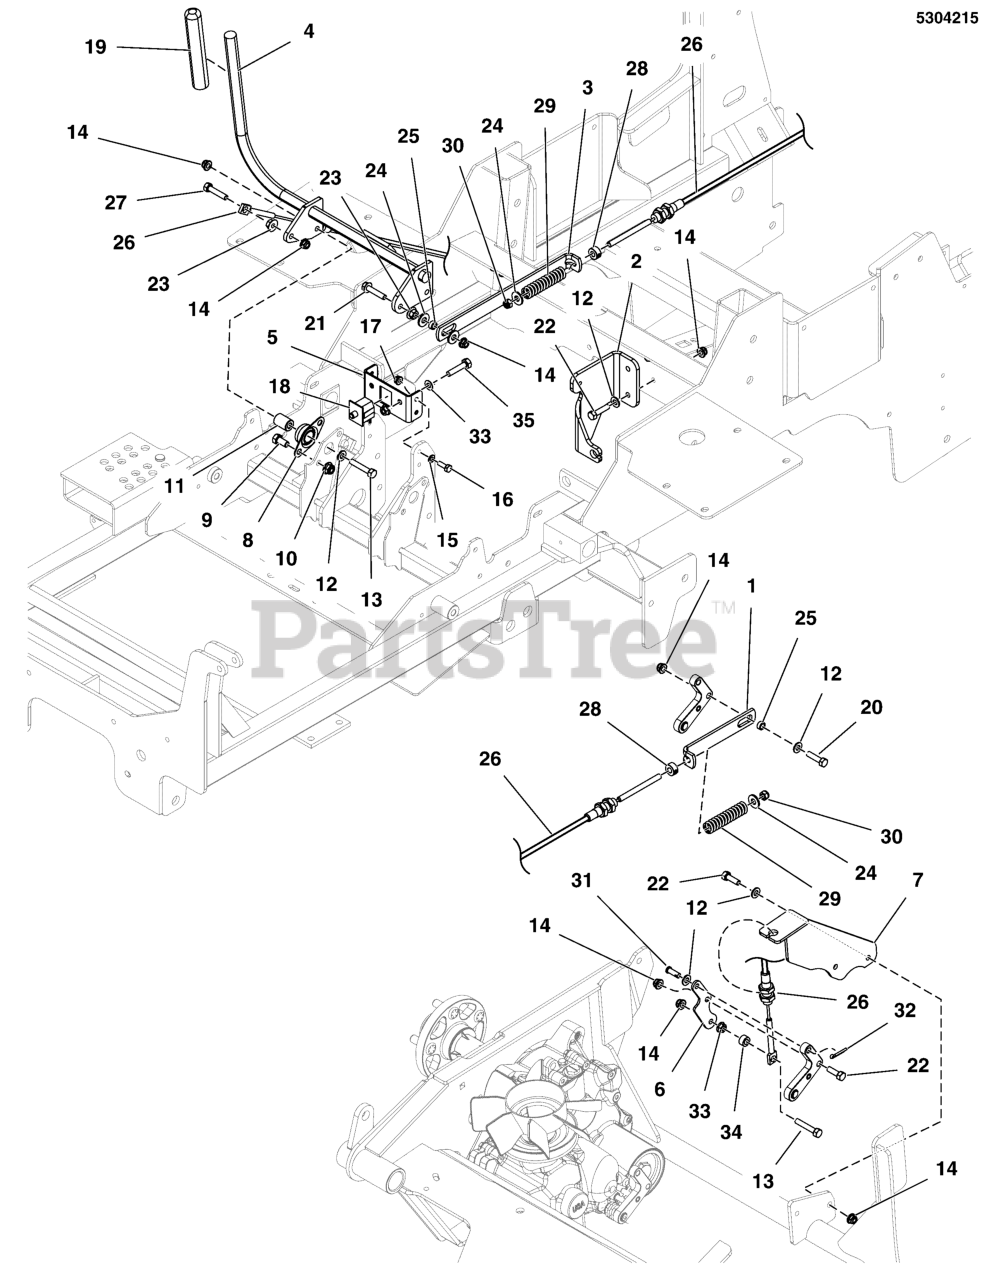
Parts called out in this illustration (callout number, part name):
1	LINK, BRAKE LOCK, RH, IS2600Z - BLK
2	MOUNT, BRAKE CABLE - RED
3	LINK, BRAKE, IS2600 - BLK
4	WELD, BRAKE SHAFT, IS2600 - BLK
5	PLATE, BRAKE STOP - RED
6	PLATE, BRAKE ARM, IS2100 - BLK
7	BRACKET, Mounting
8	BEARING, 3/4" FLANGED, BRONZE
9	BOLT, 3/8-16 X 3/4" GD5 CZ
10	NUT, 3/8-16 HEX NYLOCK FLANGE
11	SPACER, .32 X .75 X 1.06, PM
12	WASHER, 5/16" SAE
13	BOLT, 5/16-18 X 1-3/4 GD5 CZ
14	NUT, 5/16-18 HEX NYLOCK FLANGE
15	WASHER, 1/4 SAE
16	BOLT, 1/4-20 X 3/4 GD5 CZ
17	NUT, 1/4-20 HEX NYLOCK FLANGE
18	SWITCH, LOW PROF, NC/NO
19	GRIP, FOAM, 3/4 ID X 6 X .187
20	BOLT, 5/16-18 X 1-1/4 GD5 CZ
21	BOLT, 5/16-18 X 1 1/2 FLANGE
22	BOLT, 5/16-18 X 1 GD5 CZ
23	NUT, 5/16-18 HEX SERRATED FLANGE (LARGE)
24	WASHER, 5/16 USS
25	SPACER, .33 X .50 X .25, PM, CZ
26	CABLE, PARKING BRAKE, 32"
27	BOLT, 5/16-18 X 1-1/2 GD5 CZ
28	COLLAR, 5/16 SET
29	SPRING, COMP. 1/2 ID X .140 WIRE X 3.25
30	NUT, 5/16-24 HEX NYLON LOCK
31	PIN, CLEVIS, 5/16 X 1, PLATED
32	PIN, COTTER, 1/8 X 3/4
33	NUT, 5/16-18 HEX SERRATED FLANGE (SMALL)
34	SPACER, .33 X .63 X .36, PM, CZ
35	BOLT, 5/16-18 X 1-1/2 GD5 TFL
